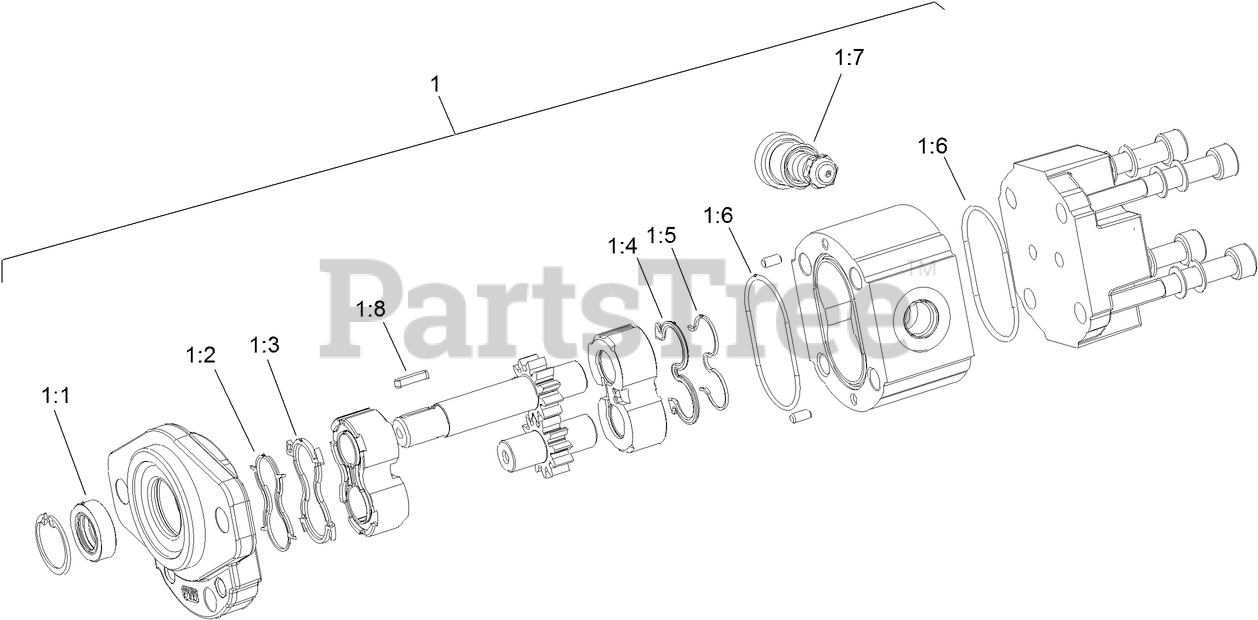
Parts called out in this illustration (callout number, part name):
1:1	SHAFT SEAL
1:2	ANTI EXTRUSION
1:3	UPPER SEAL
1:4	SEAL
1:5	ANTI EXTRUSION
1:6	O-Ring Seal
1:7	O-Ring Seal
1:8	Key
